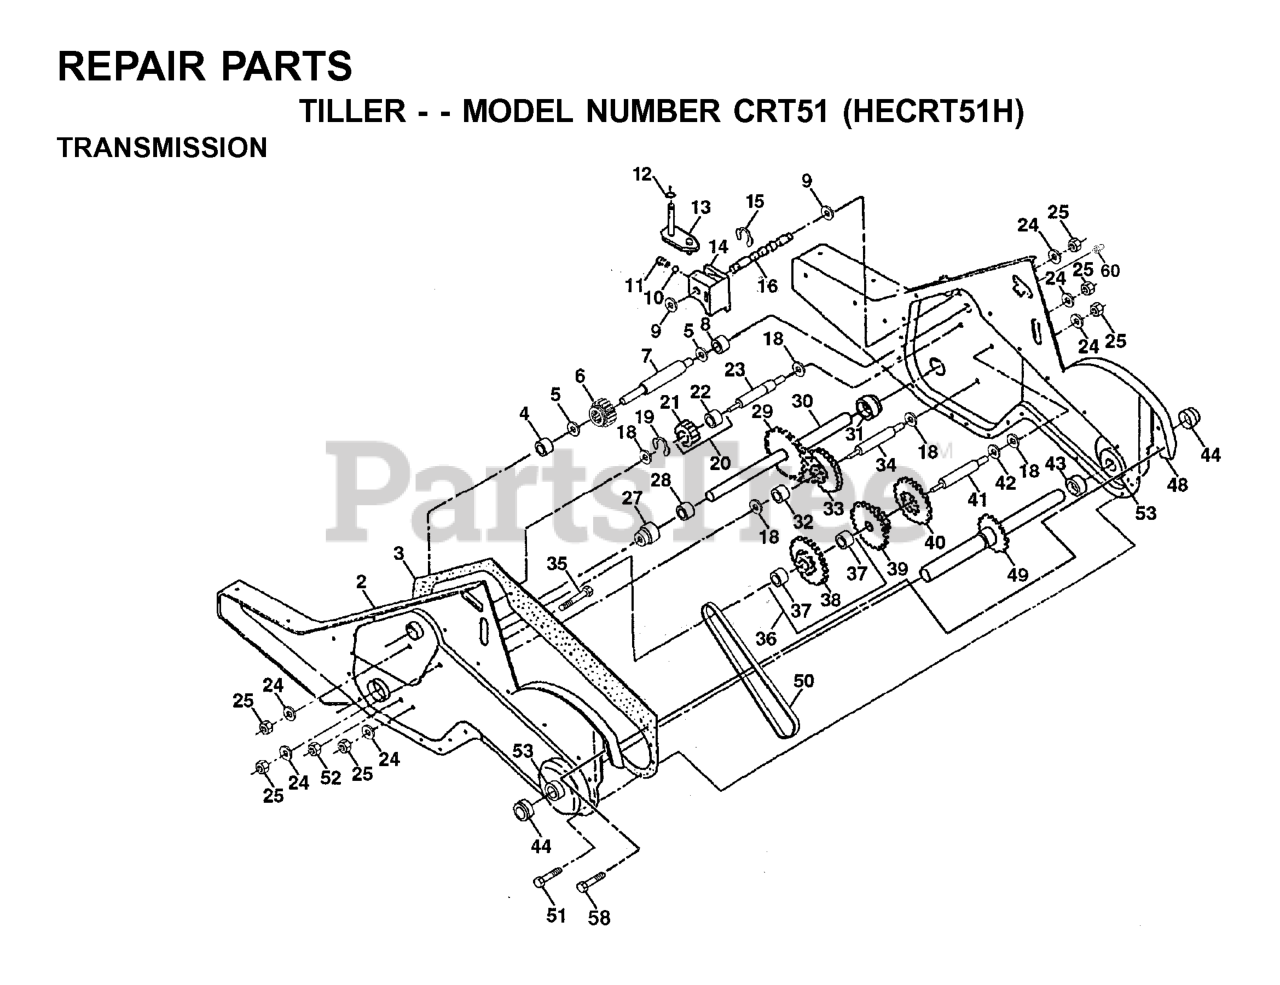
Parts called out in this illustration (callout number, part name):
1	TRANSMISSION ASSY
2	GEARCASE-LH
3	GASKET
4	NEEDLE BRNG LT
5	THRUST WASHER
6	GEAR.PINION.INPUT
7	SHAFT.INPUT."D".TILLER
8	BEARING TI
9	WASHER, SEAL (2 2)
10	STEEL BALL KIT
11	SPRING-SHIFT CRT
13	BRACKET ASM.SHIFT.CRT
14	SHIFT FORK TI
16	SHAFT.SHIFTER.TILLER
20	GEAR ASSY CRT
21	GEAR-REV IDLR CRT
22	NEEDLE BEARING TI
24	LOCKWASHER
25	NUT.ASF.HEX.7/16
27	BEARING, SHAFT LH CRT
30	GROUND SHAFT ASS'Y
31	BEARING, SHAFT RH CRT
33	SPRCKT 8 GEAR CRT
34	SHAFT.SECONDARY.REDUCTION.CRT
35	SCRW WHIZ LOK CRT
36	SPROCKET.ASM.W/BEARING.TILLER
37	BEARING
38	SPROCKET, TINE
41	SHAFT.REDUCTION.TILLER
42	BRNG RACE T
44	SEAL ASM, OIL
48	GEARCASE
49	TINE SHAFT
50	CHAIN.TILLER
51	SCREW
53	KIT.BEARING.TILLER.
58	SCREW 1/4-20X3/4
60	ZERK M
